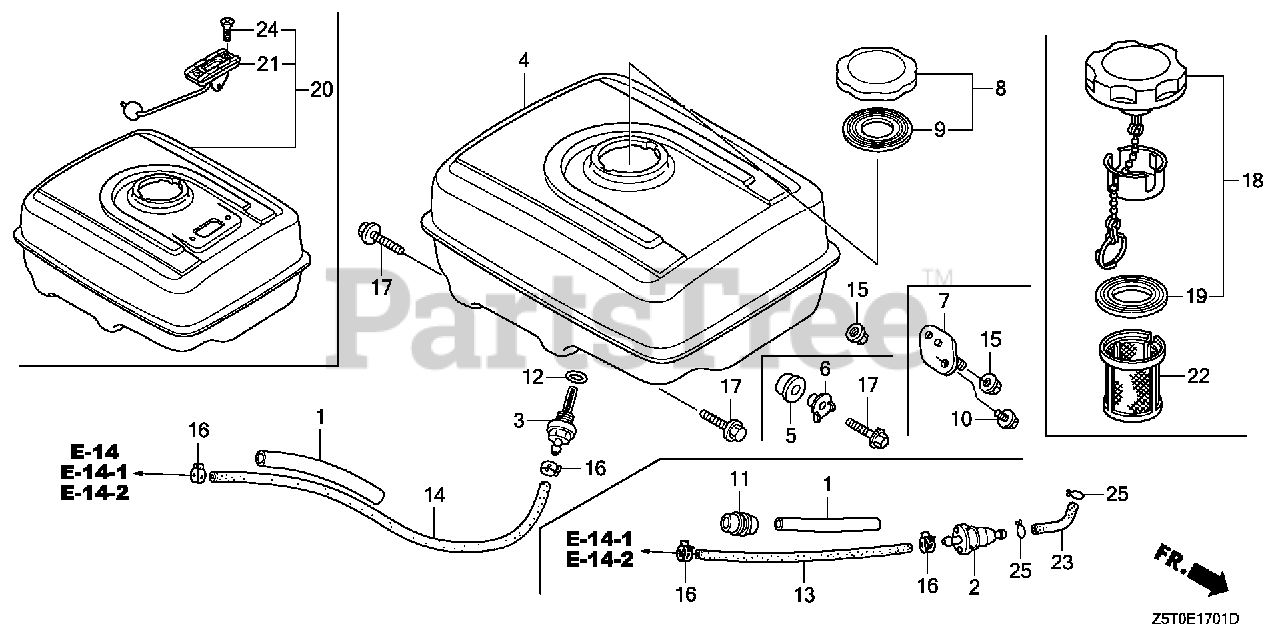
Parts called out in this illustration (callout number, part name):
1	RUBBER, SUPPORTER (107MM)
3	JOINT, FUEL TANK
4	TANK, FUEL *NH31* (MCKINLEY WHITE)
12	O-RING (13.5X1.5) (ARAI)
12	O-RING (14MM) (NOK)
14	TUBE, FUEL (4.5X235) (FKM)
15	NUT, FLANGE (8MM)
16	CLAMP, TUBE (D8)
17	BOLT, FLANGE (8X25)
18	CAP, FUEL FILLER
19	GASKET, FUEL FILLER CAP (39X62X3) (RADICON)
22	FILTER, FUEL
